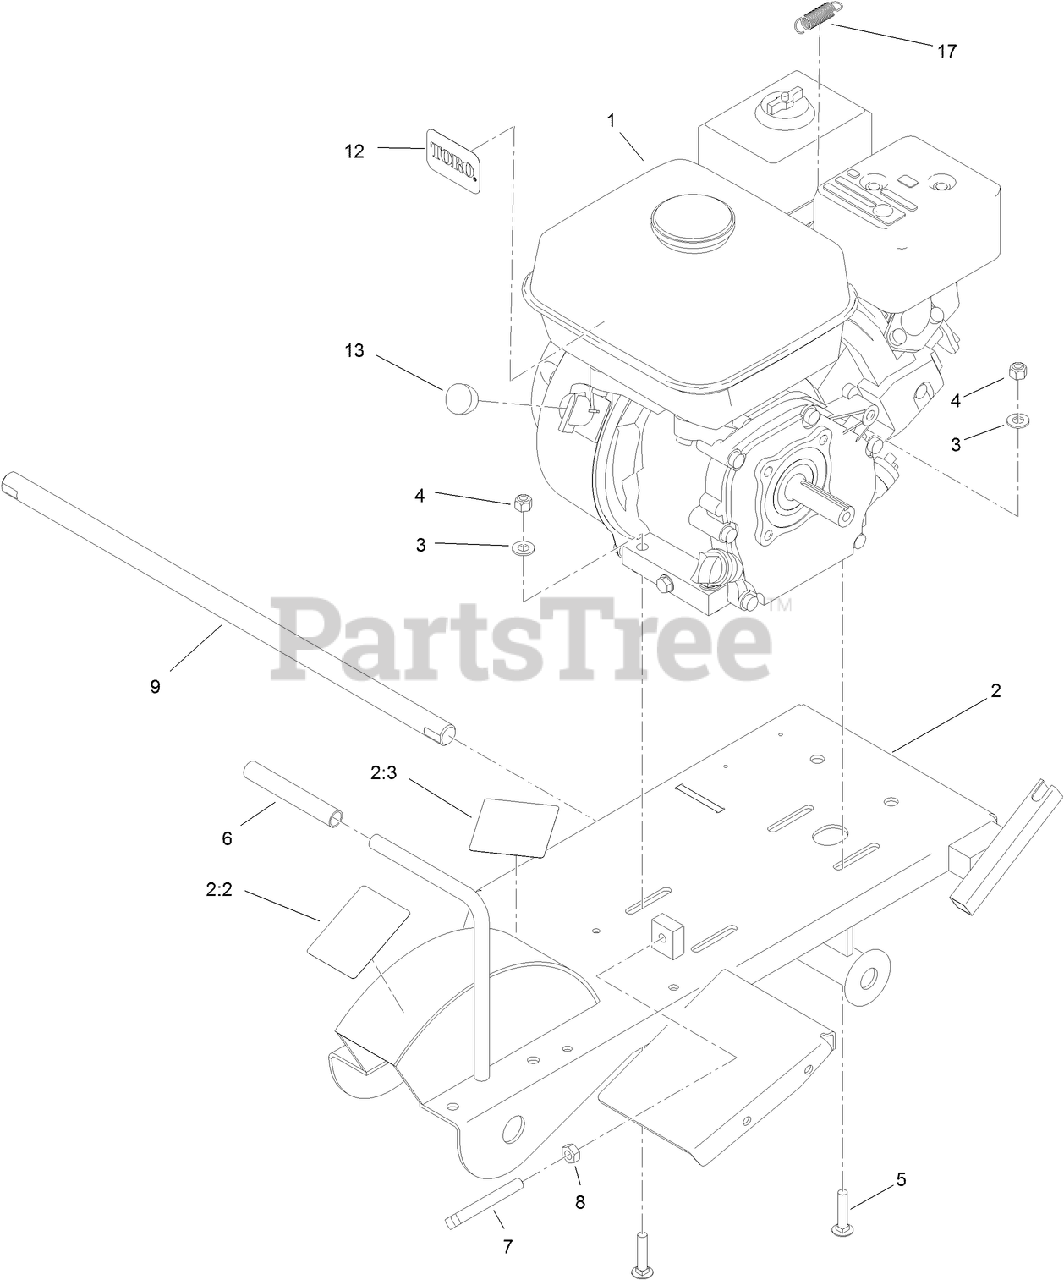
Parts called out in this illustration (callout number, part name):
2	FRAME ASM
2:2	DECAL-DANGER
2:3	DECAL-CAUTION
3	WASHER-FLAT
4	NUT-LOCK, NI
5	BOLT-CARR
6	GRIP-RUBBER
7	SCREW-SET, SQH
8	NUT-HEX
9	BAR-AXLE, WHEEL
12	Decal
13	PLUG-ENGINE
17	SPRING-EXTENSION
